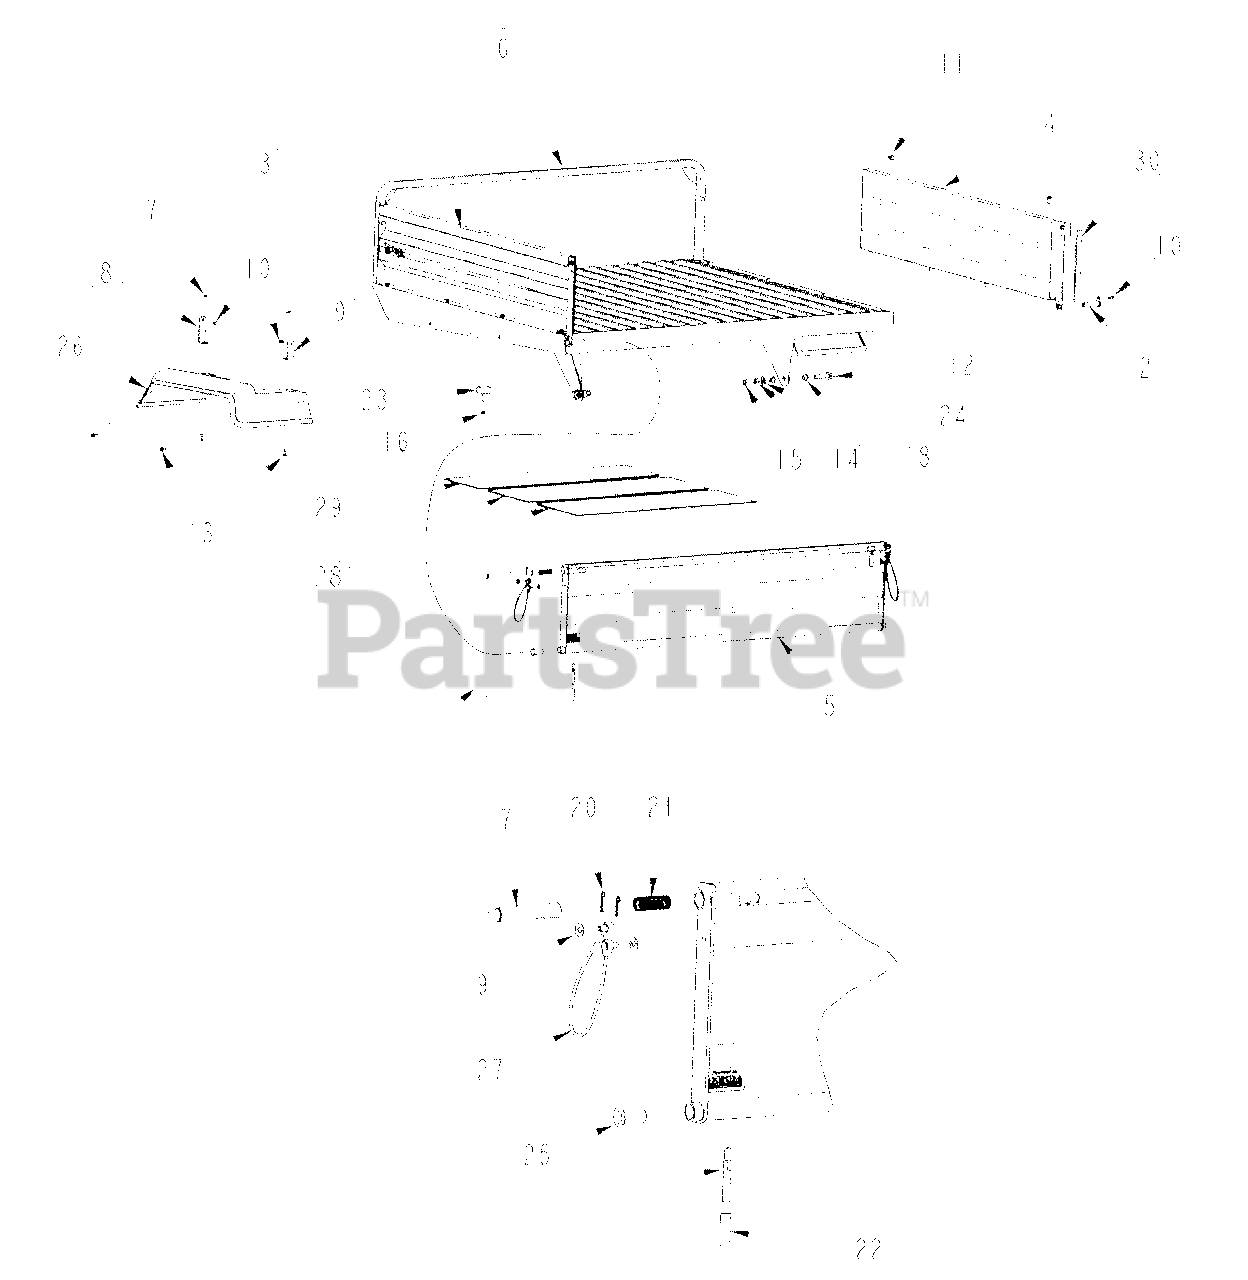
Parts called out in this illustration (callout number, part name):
1	TAILGATE LATCH HANDLE
2	WELDMENT, TAILGATE PIVOT
3	LH BED SIDE ASSY, RED 4220 Includes Decals
4	RH BED SIDE ASSY, RED 4220 Includes Decals
5	TAILGATE ASSEMBLY, RED Includes Decals, Latch & Bushings
6	BED BASE SUB-ASSY, BLACK Includes Decals, Inserts & Heat Shielding
7	LATCH PIN
8	BRACKET, FENDER MOUNT FRONT
9	BRACKET, FENDER MOUNT REAR
10	SCREW HEX SELF-TAP 1/4-20X 1/2
11	HFS 5/16-18X3/4 GR5
12	HFS 1/2-13X2 1/4 GR5 PLT
13	HFS 1/4-20X5/8 GR5 YLW
14	NUT LOCK 1/2-13 PLT
15	NUT HEX JAM 1/2-13 PLT
16	NUT HEX FLANGE 3/8-16 PLT
17	NUT HEX FLNG T-LOCK 1/4-20 YLW
18	WASHER FLAT 1/2 SAE PLT
19	WASHER FLAT 5/16 SAE PLT
20	PIN HAIR COTTER .059W 15/16LG
21	SPRING COMP .734ODX2.06X.072W
22	RUBBER TAILGATE LATCH SLEEVE
23	RUB. STOP 2" W/ 3/8X1.25 STUD
24	BUSHING 1/2IDX5/8ODX1/2 FLANGE
25	BEARING .75DX.625IDX1.5L W/FLG
26	FENDER BLACK UNIVERSAL TRUCK
27	TRUCK TAILGATE CABLE
28	HEAT SHIELD / INSUL BED
29	HEAT SHIELD / INSUL BED FRONT
30	SPONGE RUBBER, 1/4X3/4 W/PSA X 10" LG. Sold By The Foot
